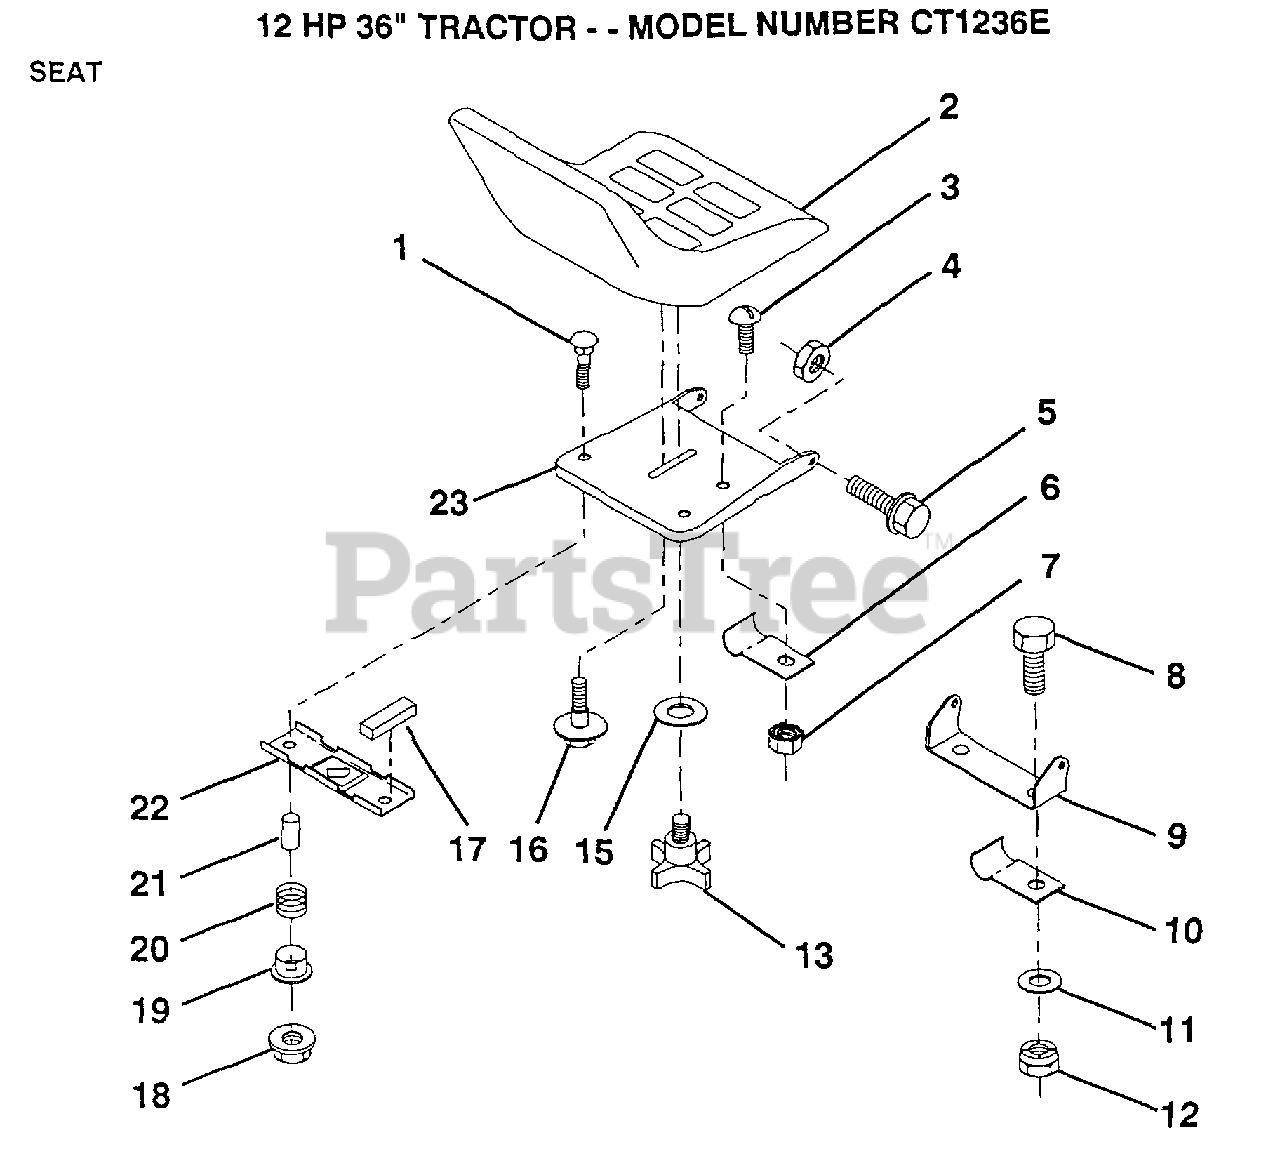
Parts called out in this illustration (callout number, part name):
7	"NUT,KEPS"
10	"CLIP,INSULATOR"
11	WASHER
13	"KNOB 1/2"" YT"
15	WASHER
16	"BOLT,SHOULDER"
17	STRIP FORM
19	BUSHING
20	SPRING
21	SPACER SPLIT
22	BRKT SWITCH
